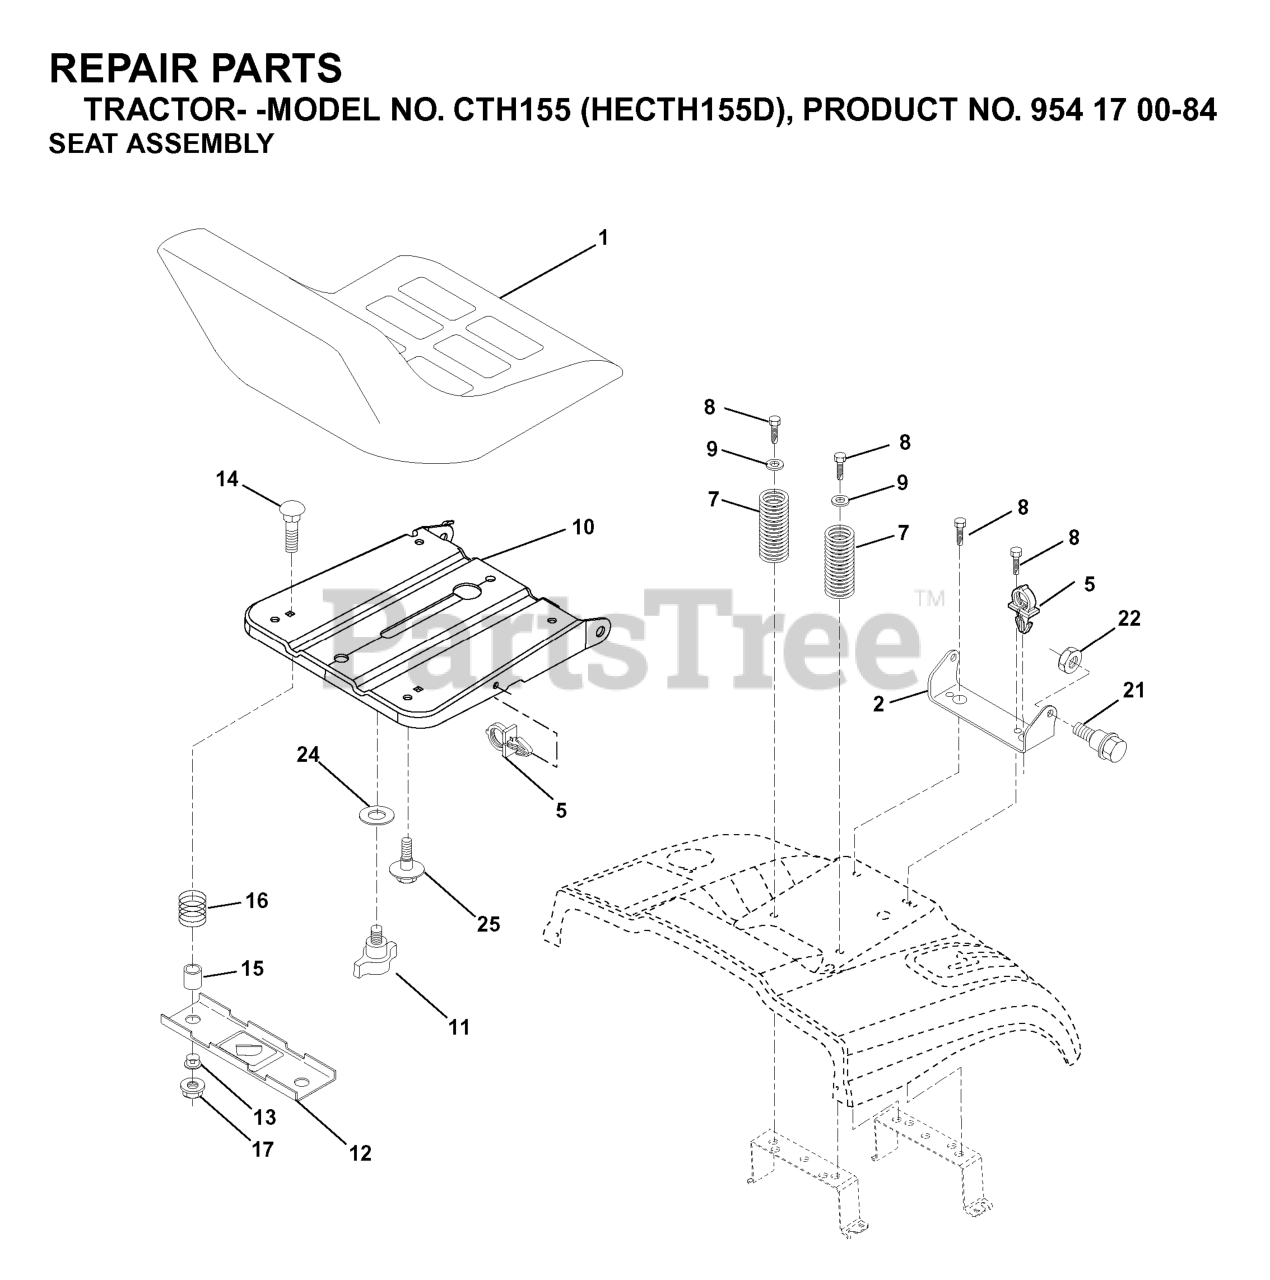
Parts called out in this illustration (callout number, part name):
1	SEAT
2	SEAT PIVOT BRKT
3	BOLT, HEX 3/8-16X1
6	NUT
7	SPRING COMPRESSION
8	SCREW 3/8-16X1
9	WASHER
10	PAN SEAT
11	KNOB.SEAT.ADJ.WINGNUT
12	BRKT SWITCH
14	BOLT.ROUND.HEAD.SQUARE.NECK
15	SPACER SPLIT
16	SPRING COMPRESSED
17	NUT T
21	BOLT.SHOULDER.5/16-18
22	NUT.71038.31-18.HEX.NYLOCK
25	BOLT,SHOULD
